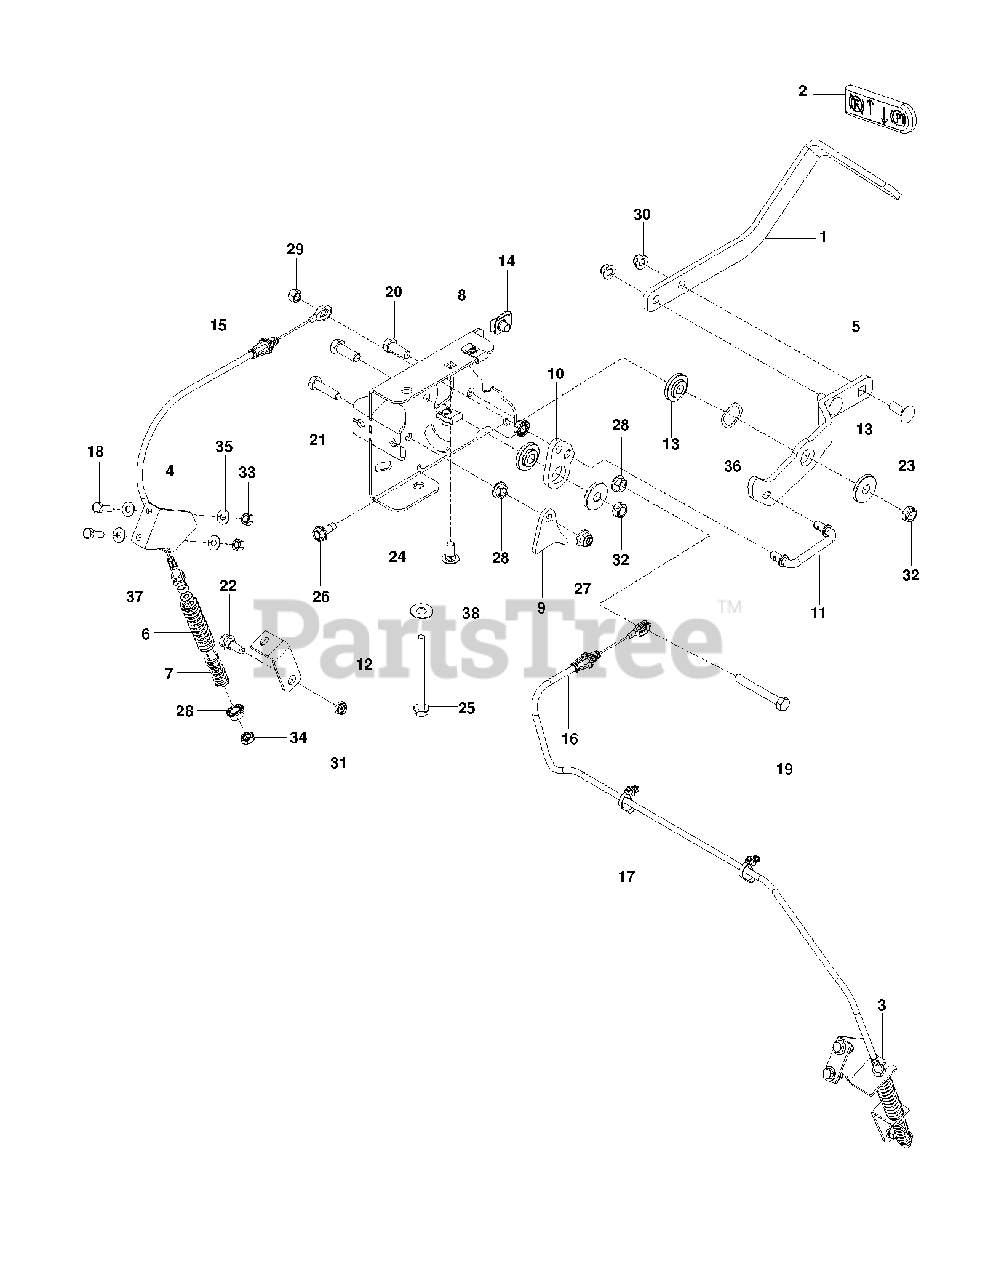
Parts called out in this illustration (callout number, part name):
1	ARM, BRAKE
2	GRIP, PARK BRAKE
3	BRKT, BRAKE RT, BLK
4	BRKT, BRAKE LT, BLK
5	LEVER, BRAKE
6	SPRING, RETURN
7	SPRING, ENGAGEMENT
8	MOUNT, BRAKE WLDMT
9	ACTUATOR, SWITCH
10	BELLCRANK, BRAKE
11	LINKAGE, BRAKE
12	BRKT, BRAKE, BLK
13	BUSHING, BRAKE
14	U-CLIP 5/16-18 NUT RETAINER
15	RP_CABLE, BRAKE, SHORT
16	RP_CABLE, BRAKE, LONG
17	TIE WRAP, 8-3/8", W/CLIP
18	HCS 1/4-20X7/8 GR5
19	HCS 5/16-18 X 2 1/2 TPBLT
20	HCS 3/8-16X1.GRD.5.ZD
21	HCS 5/16C X 1
22	BOLT, SHOULDER
23	RHSNB 3/8C X 1
24	BOLT 5/16C X 3/4" CARRIAGE
25	HHFS 5/16-18 X 3 3/4
26	BOLT 5/16-18 X 3/4
27	5/16-18 NYLOC FLANGE NUT
28	NUT 5/16C WHIZ
29	NUT 5/16 NYLOC
30	NUT 3/8-16 HEX FLG NYLOC ZD
31	5/16-18 THIN PROF NY
32	NUT HEX 3/8-16 NYLON, THIN
33	RP_NUT 1/4-20 NYLOC
34	NUT 5/16-18 HEX JAM ZD
35	WASHER 1/4 SAE
36	WASHER, .825 X 1.087, WAVE
37	WASHER 3/8 SAE FLAT
38	WASH USS FLAT 1/2
